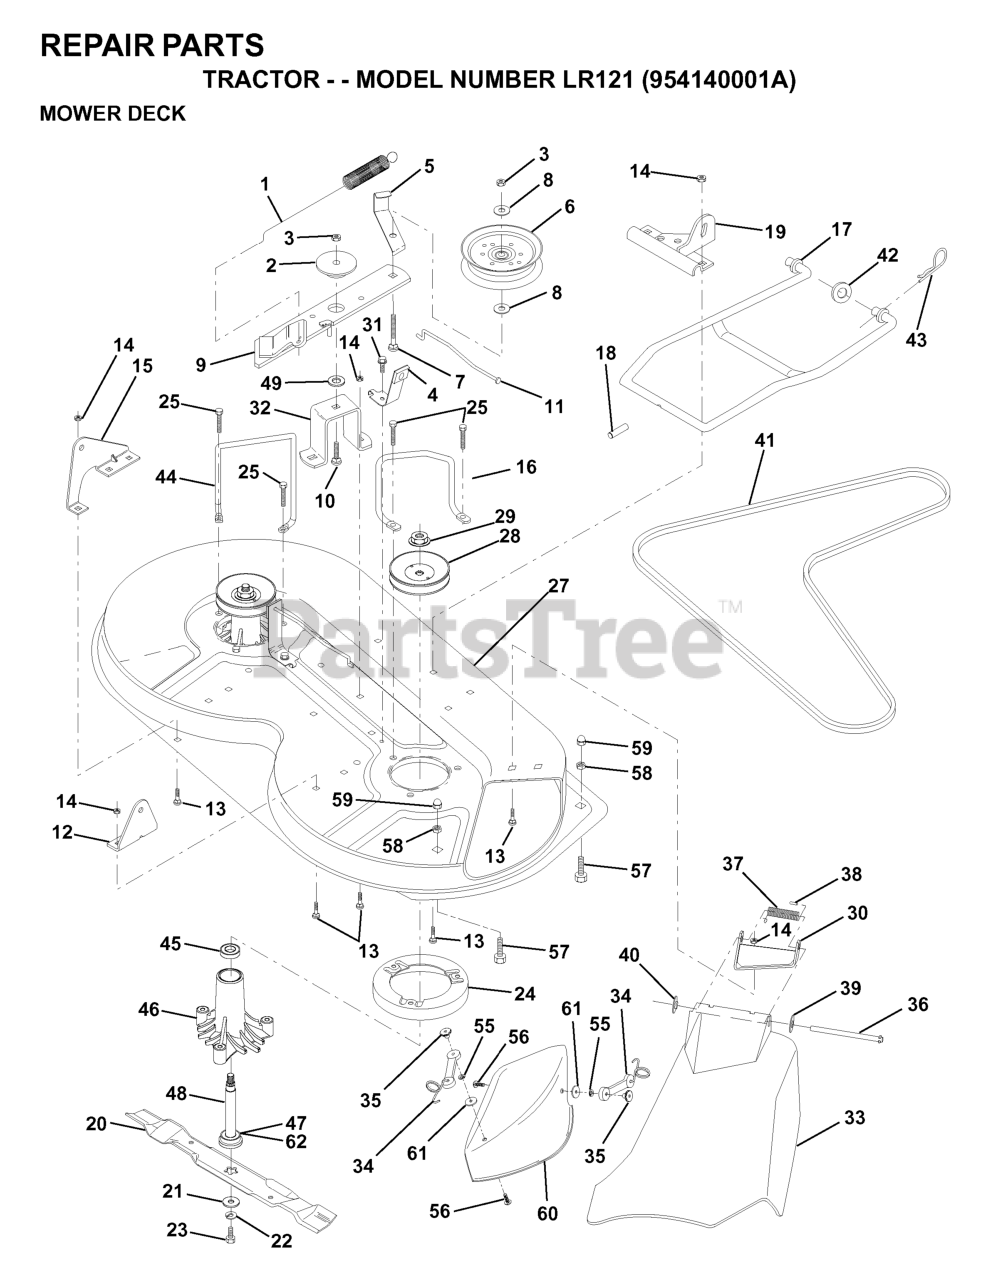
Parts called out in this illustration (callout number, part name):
1	SPRING-MOWER CLUTCH
2	SPACER RETAINER
4	BRAKE ASSEMBLY
5	IDLER BELT GUIDE
6	PULLEY.IDLER.FLAT.MOWER.BLK.PT
8	WASHER
9	IDLER ARM ASSY
10	BOLT.3/8-14X1.25
12	BRKT LIFT REAR
13	RP BOLT 5/16-18 X3/4 ZN/YEL GR
14	LOCKNUT
15	BRKT LIFT REAR LH
16	BELT KEEPER
17	MOWER LINK STABILIZER
18	PIN GROOVE
19	BRKT LINK STABILIIZER
20	BLADE.36".MULCH
21	WASHER.BLADE
22	LOCKWASHER
23	BLADE BOLT
24	STRIPPER
25	SCREW
27	MOWER HOUSING
28	PULLEY, MANDREL
29	NUT
30	BRACKET ASM DEFLECTOR
31	Screw 5/16-18 x 1/2 Hex, Self Tapping 5/16-18 x 1/2
32	SUPT,IDLER ARM
33	DEFLECTOR
34	LATCH ASSEMBLY
35	WELDNUT
36	HINGE ROD
37	SPRING TORSION
38	CAP-SLEEVE LT
39	Washer 11/32 x 5/8 x 16 Ga SD
40	NUT PUSH M
42	WASHER
43	SPRING RETAINER
46	HOUSING.MANDREL.VENTED (MACHD)
47	BEARING.BALL.#6204.(MANDREL)
48	SHAFT ASM VENT
49	HARDENED WASHER
55	LOCKWASHER #10
56	SCREW
57	BOLT GT
58	LOCKNUT
60	MULCH.COVER.36"
62	WASHER FELT
